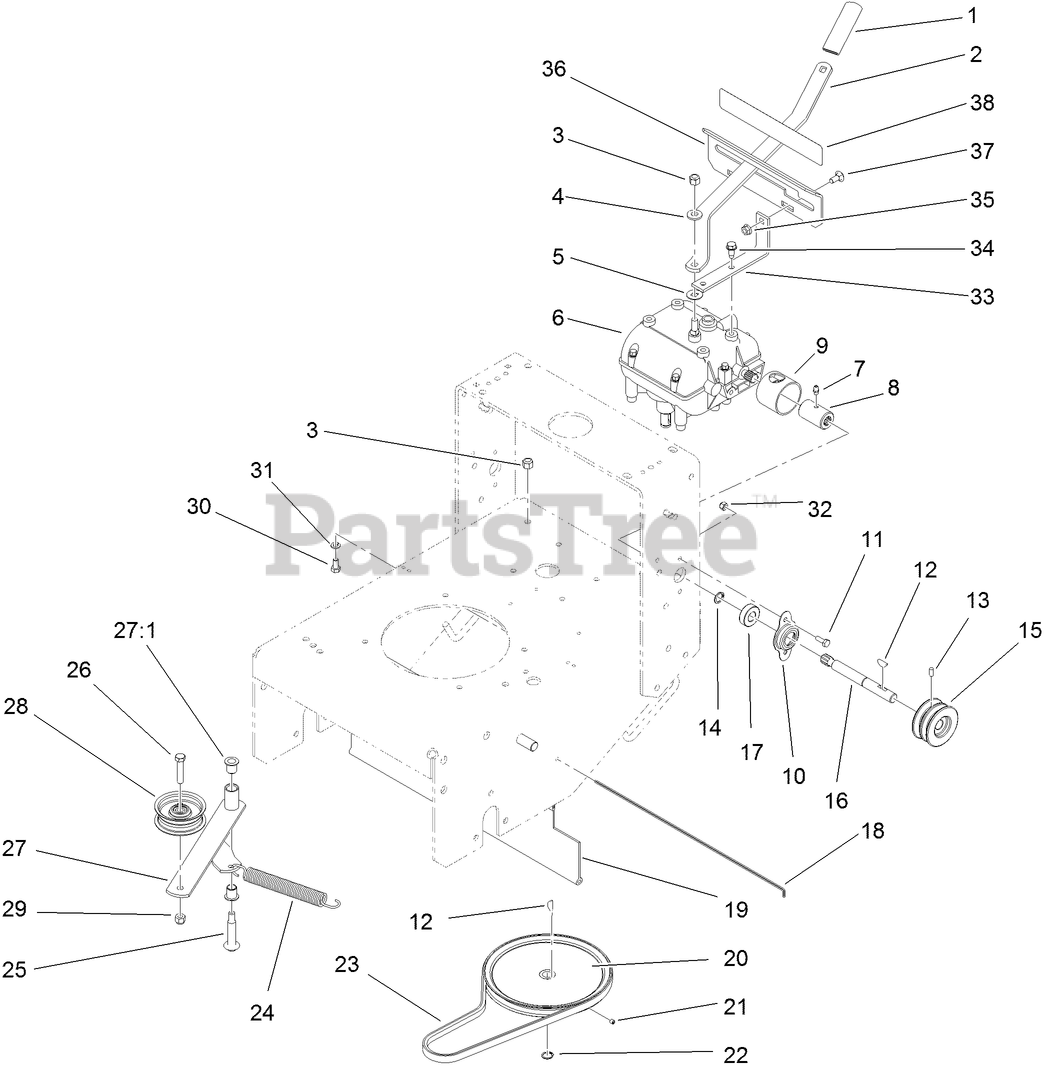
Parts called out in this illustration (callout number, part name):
2	LEVER-SHIFT
3	NUT-LOCK
4	WASHER-BELLEVILLE
5	WASHER
6	TRANSMISSION
7	FITTING-GREASE
8	COUPLER
9	GUARD-COUPLER
10	FLANGE-OUTPUT
11	SCREW-HH
12	KEY-WOODRUFF
13	SCREW-SET, HSH
14	RING-RETAINING
15	PULLEY-TRANSMISSION
16	SHAFT-OUTPUT
17	BEARING-SHAFT
18	ROD-SHIELD
19	SHIELD-TRAILING
20	PULLEY-DRIVEN
21	SCREW-HSH
22	RING-SNAP, EXTERNAL
23	V-BELT
24	SPRING-EXTENSION
25	BOLT-WHEEL
26	SCREW-HH
27	LEVER-IDLER
27:1	BUSHING-FLANGE
28	PULLEY
29	NUT-LOCK, NI
30	SCREW-HH
31	WASHER-LOCK
32	NUT-LOCK, NI
33	BRACKET-PLATE, SHIFT
34	SCREW-HWHTF
35	NUT-HF, NI
36	PLATE-SHIFT
37	BOLT-CARR
38	DECAL-SPEED, GROUND
